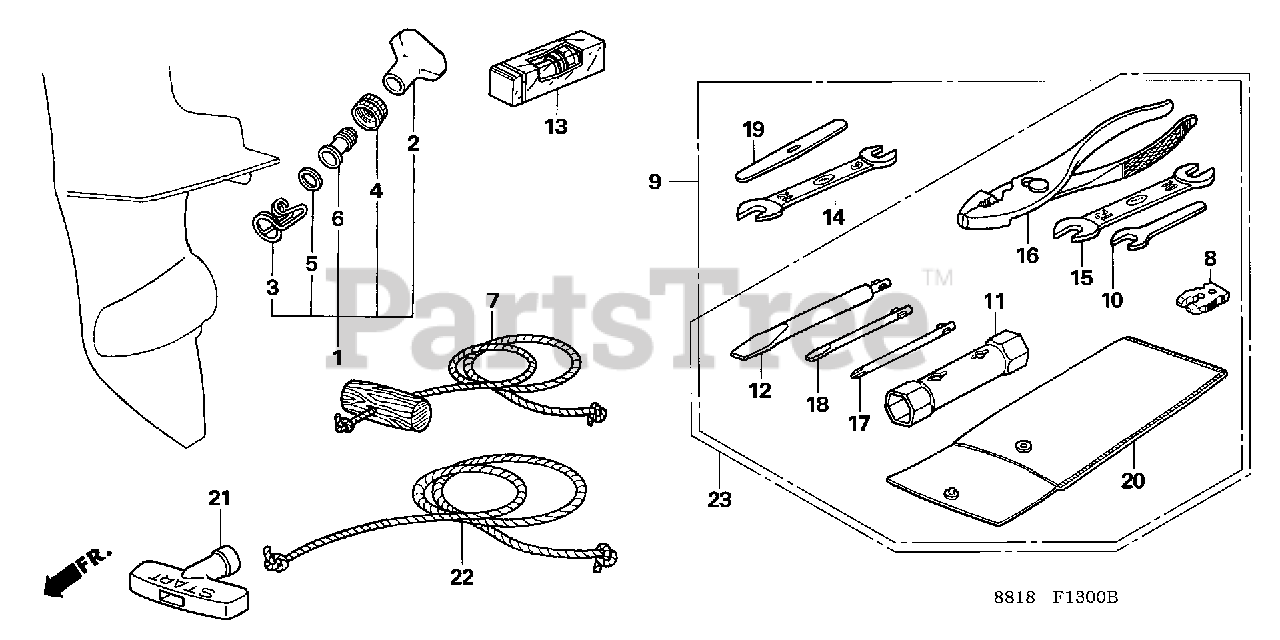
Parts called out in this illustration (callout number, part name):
1	WATER MOUTH KIT
2	MOUTH, WATER
3	CLIP, WATER MOUTH
4	NUT, WATER MOUTH
5	SEAT, WATER MOUTH
6	JOINT, HOSE
7	ROPE, STARTER
8	CLIP, EMERGENCY LOCK
9	TOOL KIT (N/A: SEE COMPONENTS)
10	SPANNER (8MM) (NOT AVAILABLE)
11	WRENCH, BOX (P18X19) (NOT AVAILABLE)
12	SCREWDRIVER, CHECK BOLT
13	SPARK PLUG (DR-5HS) (NGK)
14	SPANNER (9X12)
15	SPANNER (10X12)
16	PLIERS (135) (KOWA)
17	DRIVER 1, PLUS SCREW (NO.2)
18	DRIVER 3, MINUS SCREW (NO.2)
